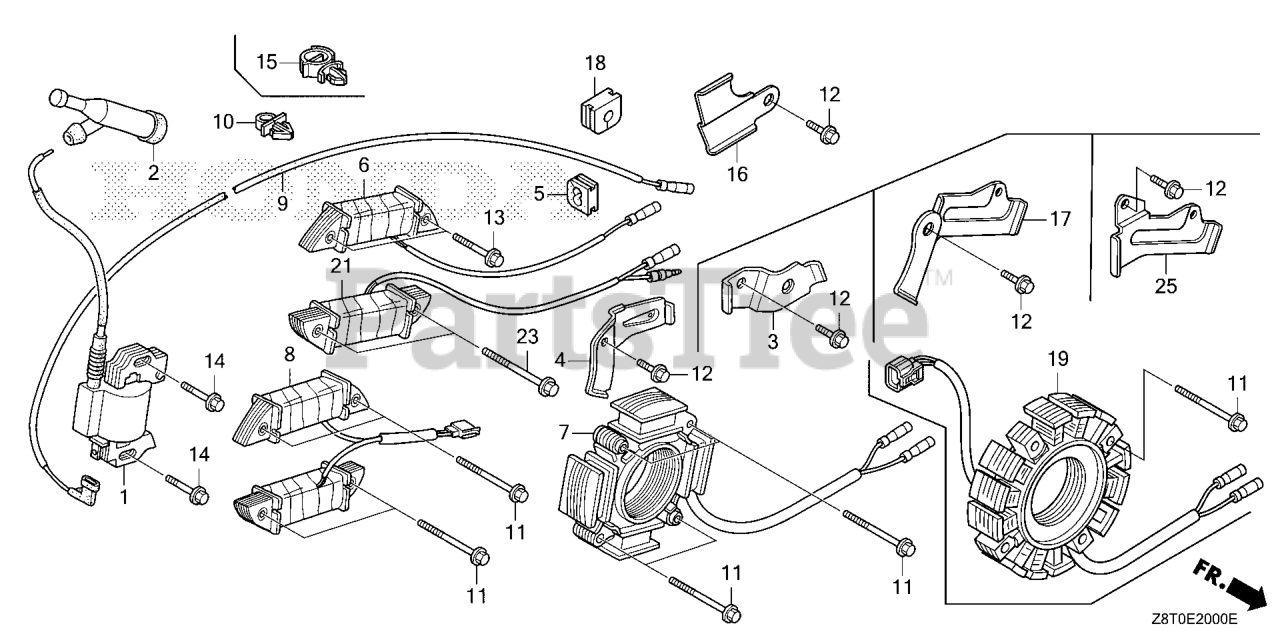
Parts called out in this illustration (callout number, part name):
1	COIL ASSY., IGNITION
1	COIL ASSY., IGNITION (MAHLE)
2	CAP ASSY., NOISE SUPPRESSOR (NGK Y-EZD)
5	GROMMET, WIRE
14	BOLT, FLANGE (6X28) (CT200) Use up to Engine SN 1530314.
15	CLIP, WIRE HARNESS
